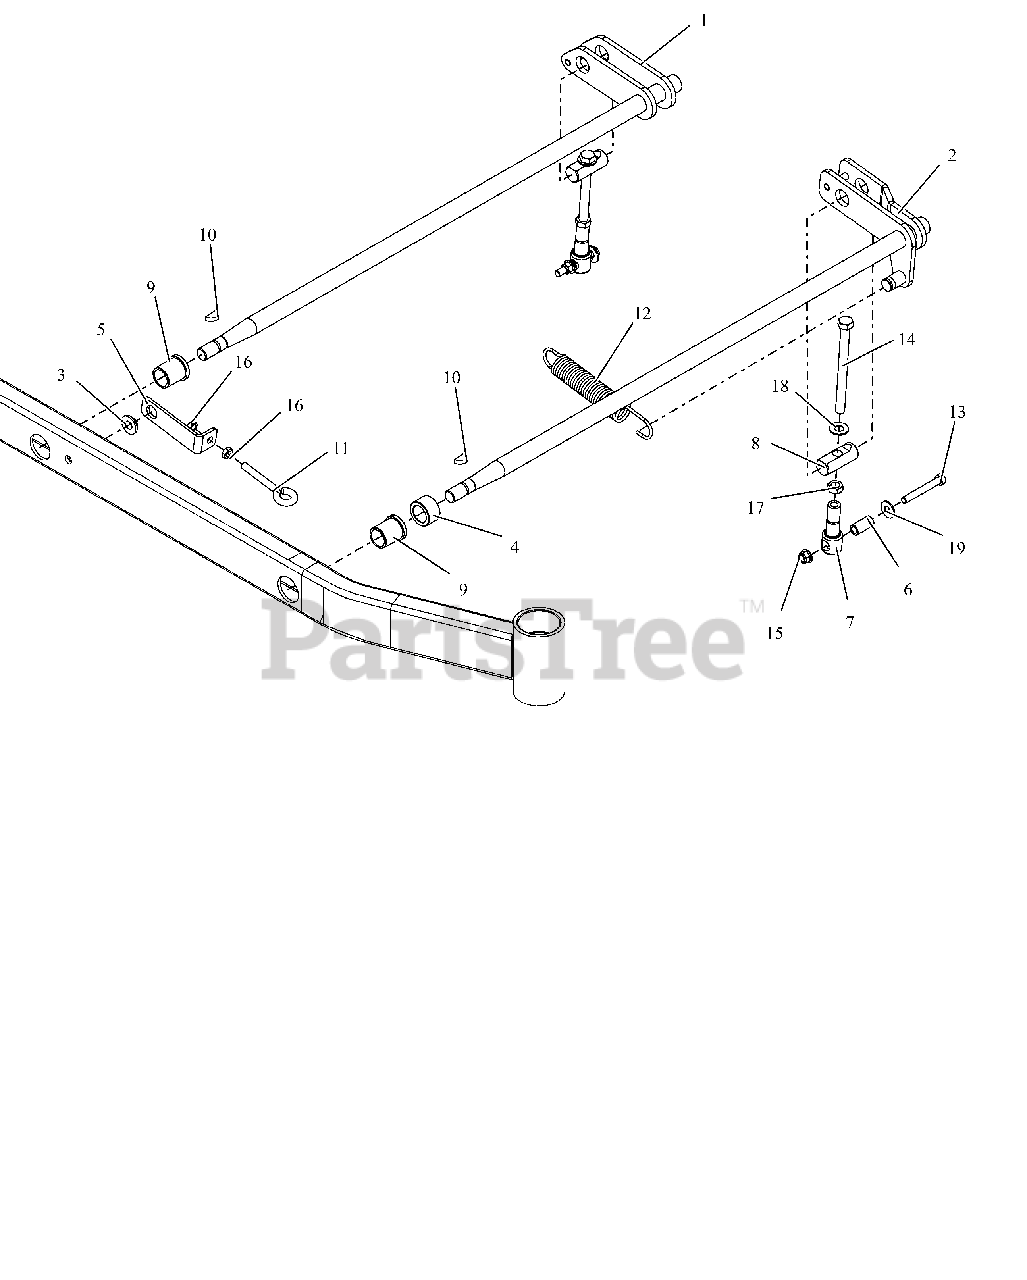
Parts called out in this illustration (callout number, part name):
1	REAR LH DECK LIFT ARM WMT- LF
2	FRT LH DECK LIFT ARM WMT- LF
3	BSHG-FLG .515X.750X.310X1.120
4	SPACER, 1.500 X 1.000 X .880
5	SPRING ANCHOR BRACKET - RED
6	SPACER, DECK LEVELING
7	LINK, DECK LIFT FORMED
8	PIN, DECK LIFT
9	BSHG-FLG 1.00X1.25X1.50X1.50
10	KEY-WDRF .25X1.00 HRD #15
11	BLT-EYE .375-16X2.50 YWZC
12	SG-TENS .162X1.25X8.25 WLD 25
13	BLT, HEX .38-16X2.75 G8 ZCC
14	BLT, HEX .50-13X6.00S G5 ZCC
15	NUT,NYL-FLG .38-16 GF ZCC
16	NUT-JAM .375-16 G2 ZCC
17	NUT-JAM .500-13 G2 ZCC
18	WSHR, FLT .557X1.040X.102 ZCC
19	WSHR,FLT .438X1.00X.083 ZCC
